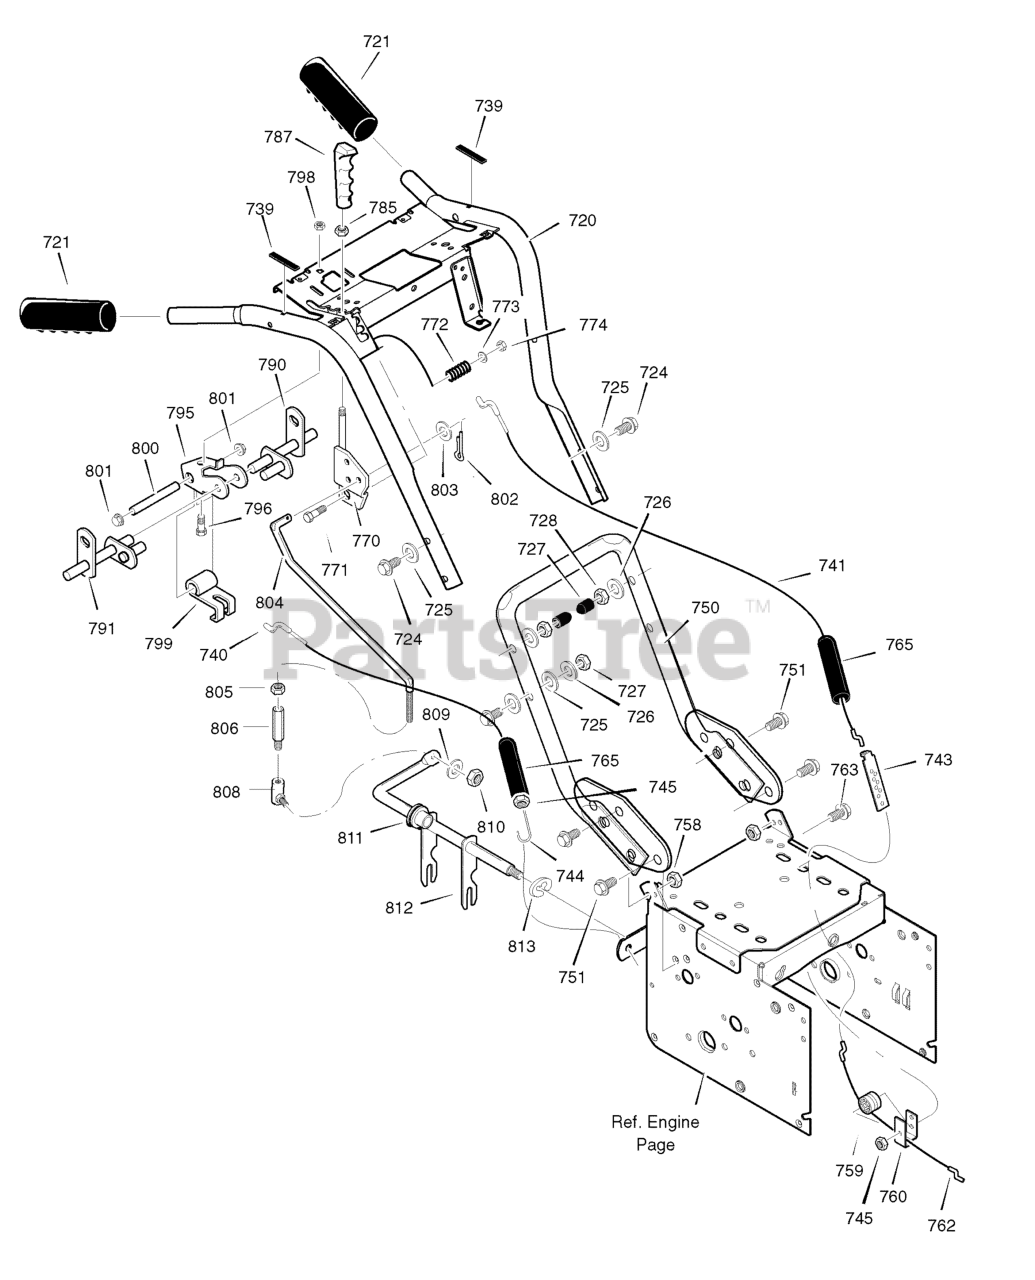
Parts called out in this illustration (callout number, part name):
720	ASSEMBLY, HANDLE
721	GRIP HANDLE
724	SCREW
725	WASHER, Flat, 13/32
726	WASHER
727	NUT
728	STOP, PLASTIC
739	BUMPER
740	CABLE, AUGER CLUTCH
741	CABLE, DRIVE
743	BRACKET, CABLE ADJUST
744	SPRING, CLUTCH
745	NUT, HEX
750	HANDLE, LOWER
751	SCREW
758	NUT, HEX
759	SPOOL, CABLE
760	BRACKET, SPOOL
762	CABLE, LOWER DRIVE
763	BOLT, HEX 1/4-20 X 1.5
765	BOOT, CABLE
770	BRACKET, SHIFT
771	SCREW
773	WASHER, Flat, 13/32
774	NUT, HEX
785	NUT, HEX
787	KNOB, SHIFT
790	ROD, ASSEMBLY LH
791	ROD, ASSEMBLY RH
795	BRACKET, CAM
796	SCREW
798	NUT, NYLOCK
799	CAM LOCK
800	PIN, SPRING PIVOT
801	NUT, PUSH ON
802	PIN, COTTER
803	FLATWASHER
804	ROD, SPEED CONTROL
805	NUT, 5/16-18
806	ADAPTER, ROD
808	BALLJOINT, STEEL
809	WASHER
810	NUT, 5/16-18
811	BEARING, FLANGE
812	ROD, YOKE
813	RETAINER, RING
